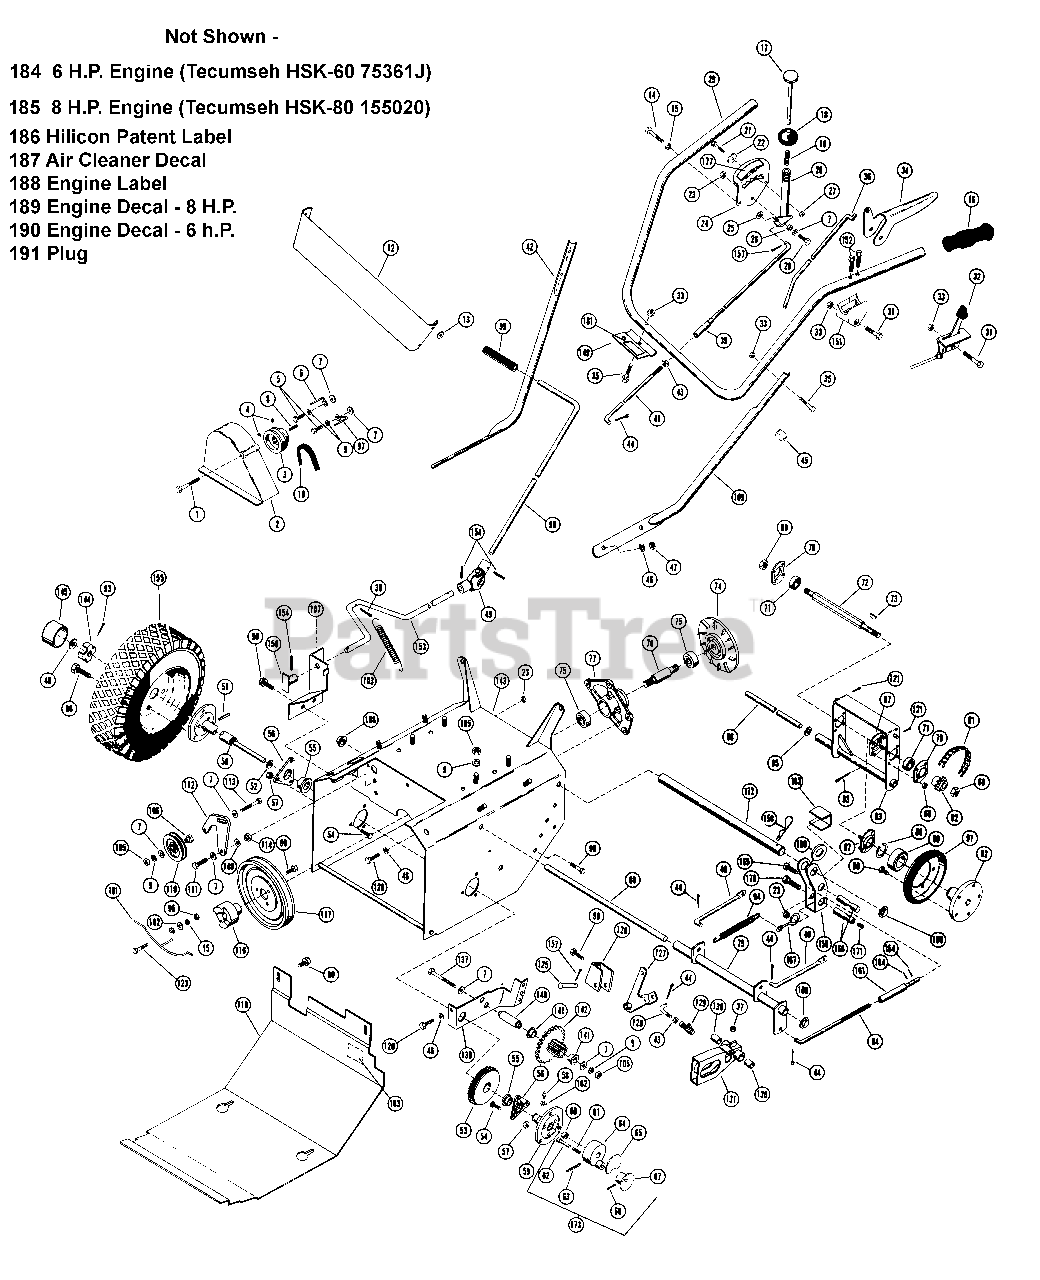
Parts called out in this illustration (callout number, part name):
1	BLT-HFWH .31-24X3.62 PL
2	OUTER BELT GUARD
3	ENGINE SHEAVE
4	SCR-SET .32-18X.38 SKHCUPNL OH
5	BLT-HEX .31-24X.75 PL GR5
6	R H BELT FINGER
7	WSHR-FL-STL .38X.875X.083 PL
8	KEY-SQ .188X1.0X.188 SAE 8630
8	KEY-STR .25X1.75X.25
9	WSHR-LK .312X.097 PL HVY
10	V-BELT, SAE 380-RAW EDGE
12	HANDLE BAR PANEL
13	HANDLE BAR WASHER
14	BLT-HEX .25-20X1.25 PL GR5
15	WSHR-LK .250X.077 HVY PL
16	GRIP
17	SHIFT RELEASE HANDLE
18	SHIFT BALL
19	SG-COMP ??X.44X?? WLD 10
20	SHIFT HANDLE
21	BLT-HEX .25-20X1.25
22	WSHR-FL-STL .281X1.250X.048PL
23	NUT-LK .312-18 GR A PL
24	SHIFT QUADRANT
25	WSHR-FL-STL.406X.812X.065PL
26	SPACER BUSHING .5 X .32 X .21
27	NUT-LK TOP .250-20 PL
28	BLT-HEX .31-18X.75 PL GR2
29	UPPER HANDLE BAR
30	PIN-COTR .12X.50 PL
31	BLT-HEX .25-20X1.75 PL GR2
32	THROTTLE CONTROL
33	NUT-LK-CTR .250-20 PL
34	CLUTCH HANDLE
35	BLT-HEX .25-20X1.50 PL GR5
36	CLUTCH ROD
37	NUT-LK-CTR .312-24 PL
39	SHIFT ROD
40	CLUTCH LINK
41	LOWER SHIFT ROD
42	R H LOWER HANDLE BAR
43	NUT-HEX .312-24 PL
44	PIN-COTR .09X.75 PL
46	WSHR-LK .375X.115 HVY PL
47	NUT-HEX .375-16
48	PUSHNUT
49	UNIVERSAL JOINT ASSEMBLY
50	R H AXLE SHAFT
51	PIN-ROLL .188X1.25
52	WSHR-FL-STL .880X1.380X.062
53	DIFFERENTIAL ASSEMBLY
54	SCR-SLTR-SERNK .25-20X.62 PL
55	BSHG-FLG.875X1X.625X1.250 BR
56	SUPPORT, BEARING
57	NUT-LK-FLG .250-20 PL
58	SPIN DRIVE ZERK FITTING
59	L H AXLE ASSEMBLY
60	BSHG-SLV .562X.625X.625 BRZ
61	SG-COMP .028X.34X1.062 WLD75
63	PIN-GRV .250X1.75 TP C
64	LOCKOUT HUB
65	DIFFERENTIAL LOCK LABEL
66	PIN-ROLL .093X1.00
68	NUT-LK-CTR .50-20 PL
69	NUT-LK DUAL FACE 10-24 PL
70	BEARING FLANGE
71	BRG-BALL .500X1.38X.437
72	HEX SHAFT
73	KEY-WDRF .125X.625X.250 SAE5
74	DRIVE PLATE
75	BRG-BALL .750X1.750X.50
76	SPINDLE
77	BEARING HOUSING
79	FORK CLUTCH LEVER
81	ROLLER CHAIN
82	9 TOOTH SPROCKET
83	DISC BRACKET
84	ADJUSTMENT LINK
85	WSHR-FL-STL .505X.875X.024 PL
86	BRACKET PIN
87	BEARING FLANGE
88	RG-RTNG-EXT 1.250X.050
89	BRG-N-THRST 1.26X2.18X.63
90	BLT-SERHFWH .31-18X.50 PL
91	FRICTION DISC
92	FRICTION DISC HUB
93	PIN-COTR .12 X 1.25 PL
94	SG-TENS .072X.50X5.31 WLD 25
95	NUT-HEX .250-20 PL
96	BLT-WHL .50-20X.75 GR5 PL
97	L H BELT FINGER
98	ATTACHMENT CLUTCH HANDLE
101	BELT FINGER
102	WSHR-FL-STL.312X.734X.065PL
103	SG-TENS .125X.437X5.5 WLD 20
105	NUT-HEX .312-18
106	BEARING SPACER
107	CLUTCH BRACKET
108	CAP, .50 ROD YWZC
109	L H LOWER HANDLE BAR
110	IDLER
111	BLT-HEX .31-18X1.25 PL GR2
112	IDLER ARM
113	BLT-HEX .31-18X1.75 PL GR2
114	SHOULDER SPACER
116	JAW COUPLING
118	BOTTOM COVER
120	BLT-HEX .38-16X.75 PL GR2
121	PIN-HAIR INT .06X.18X.77
122	CLUTCH ROD
123	BLT-HEX .25-20X.75 PL GR2
125	CLEVIS PIN
126	LEVER BRACKET
127	TRANSFER LEVER
128	CONNECTING LINK
129	BALL JOINT
130	BSHG-SLV .500X.625X.500 BR
131	SERVICE SLIDING FORK ASSM
137	BLT-HEX .31-18X2.75 PL GR2
138	BRACKET
140	PINION STUB SHAFT
141	BSHG-FLG .625X.750X.500X.875BR
142	PINION AND SPROCKET ASSY.
143	TRACTOR FRAME
144	SPINDLE CUP
145	HUB CAP
148	WSHR-FL-STL .505X.875X.024 PL
149	ROD HANGER BRACKET
150	CLUTCH INTERLOCK LEVER
151	HANDLE PIVOT
152	SCR-TAP 12-14X1.50 CROVH PL BT
153	ENGAGEMENT ROD
154	PIN-ROLL .125X.75
155	TIRE & WHEEL ASSEMBLY GOODYEAR
155	TIRE 4.10/3.50X6
155	WHL 6 IN O.D.
157	PIN-COTR .12X1.0 PL
158	PIN-COTR .09X1.0 PL
159	CLUTCH ENGAGEMENT YOKE
160	WSHR-FL-STL .505X1.000X.062
161	ADJUSTMENT TUBE
162	WSHR-LK .250X.047 LT PL
163	ADAPTER SPACER
164	PIN-ROLL .125X.50
167	SPRING WIRE
168	ROD ADAPTER
169	SCR-SET .32-18X.50 SQHCUP OH
170	BLT-HEX .31-18X.63 PL GR 2
171	SCR-SET .32-18X.38 SKHCUPNL OH
172	CLUTCH ROD
173	DIFFERENTIAL LOCKOUT HUB ASSEM
174	CARBURETOR COVER
177	SNO THRO SHIFT LABEL
181	IN OUT DECAL
183	DISC ADJUSTMENT DECAL
184	6 H.P. Engine(Tecumseh HSK-60 75361J) orReplacement
185	8 H.P. Engine(Tecumseh HSK-80 155020) orReplacement
189	8 H P ENGINE DECAL
190	6HP ENGINE DECAL
